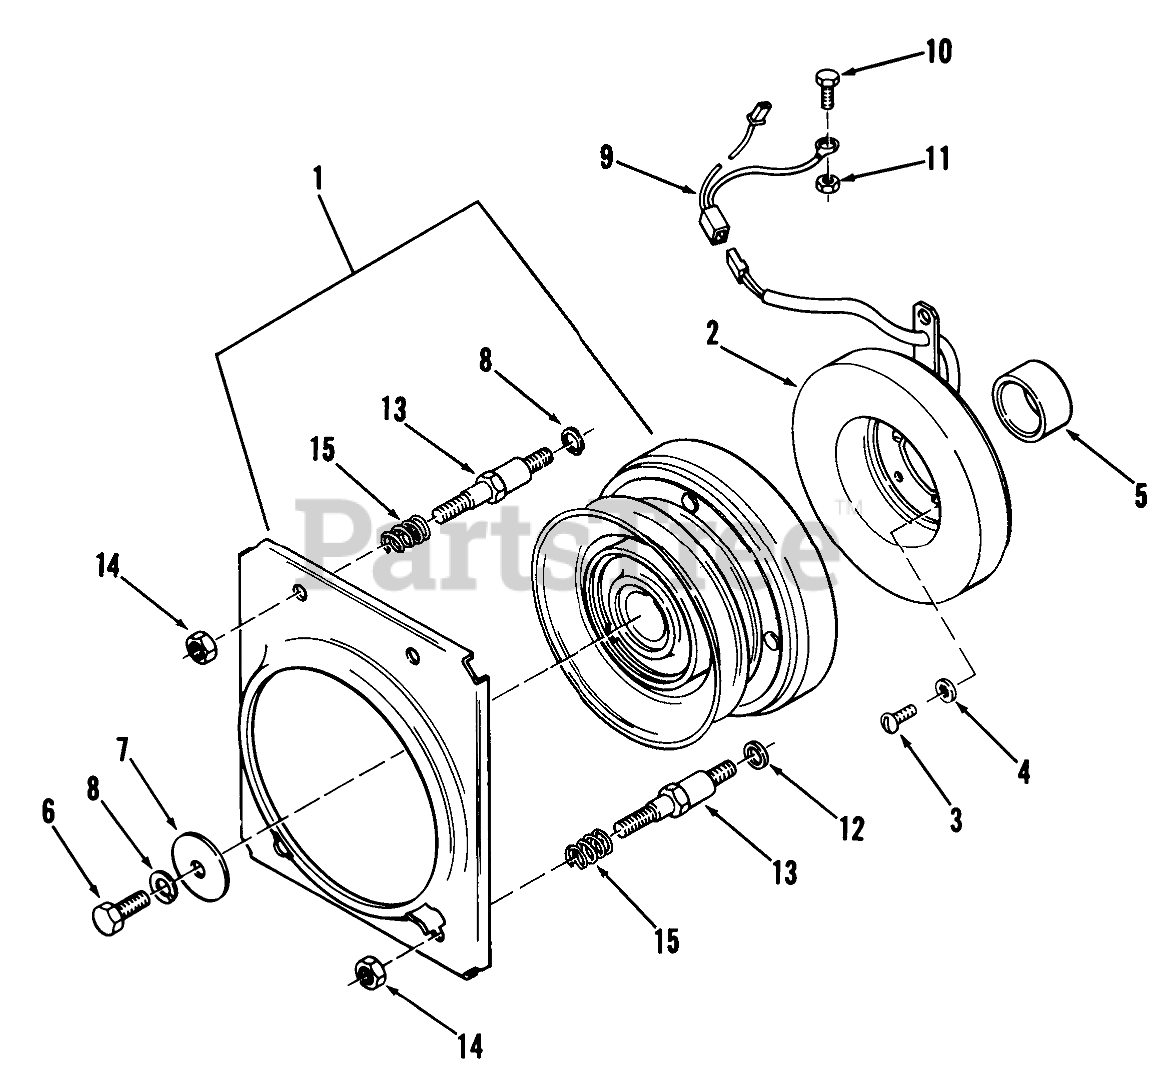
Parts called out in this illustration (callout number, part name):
1	Rotor Assembly
2	Field Assembly
3	Screw
4	Lockwasher Internal
5	Sleeve
6	BOLT
7	Washer .406 x 1.75 x .187
8	LOCKWASHER
9	Assy-Wire and Plug
10	Bolt
11	Nut
12	Washer-Copper
14	Nut
15	Spring
